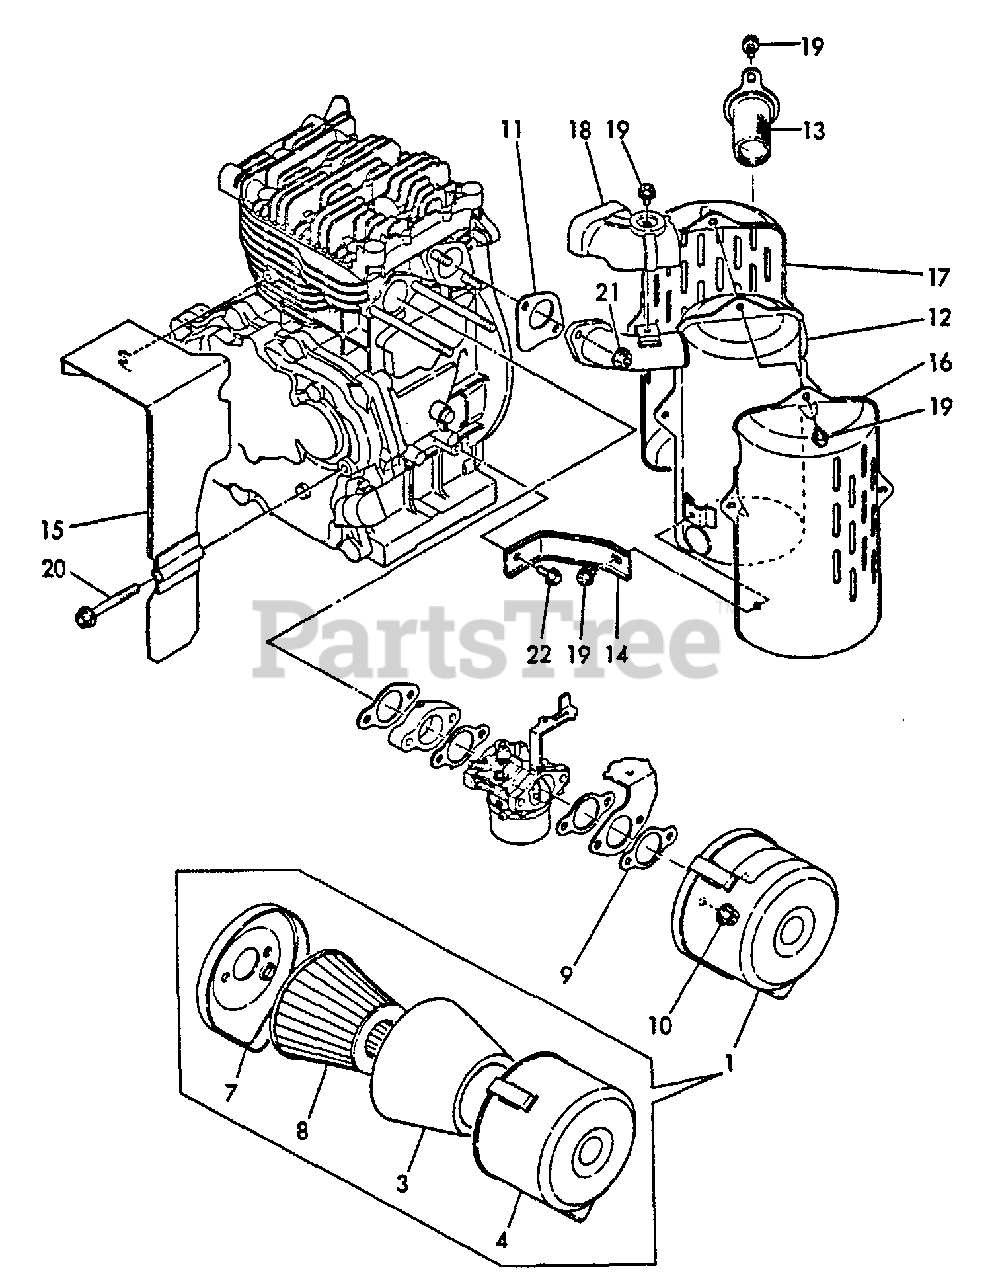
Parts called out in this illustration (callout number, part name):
1	AIR CLEANER ASSY
3	FILTER, AIR
4	BODY ASSY
7	PLATE, PREVENT
8	ELEMENT (2ND)
9	GASKET, INTAKE
10	NUT - 8
11	GASKET, EXHAUST
12	MUFFLER
13	SCREEN, SPARK ARRESTOR
14	STAY, MUFFLER
15	PLATE, GUIDE
16	COVER-A, MUFFLER
17	COVER-B, MUFFLER
18	COVER-C, MUFFLER
19	BOLT - 6X8 -- PLATED
20	BOLT - 8X60 -- PLATED
21	NUT - 8
22	BOLT - 6X8 -- PLATED
